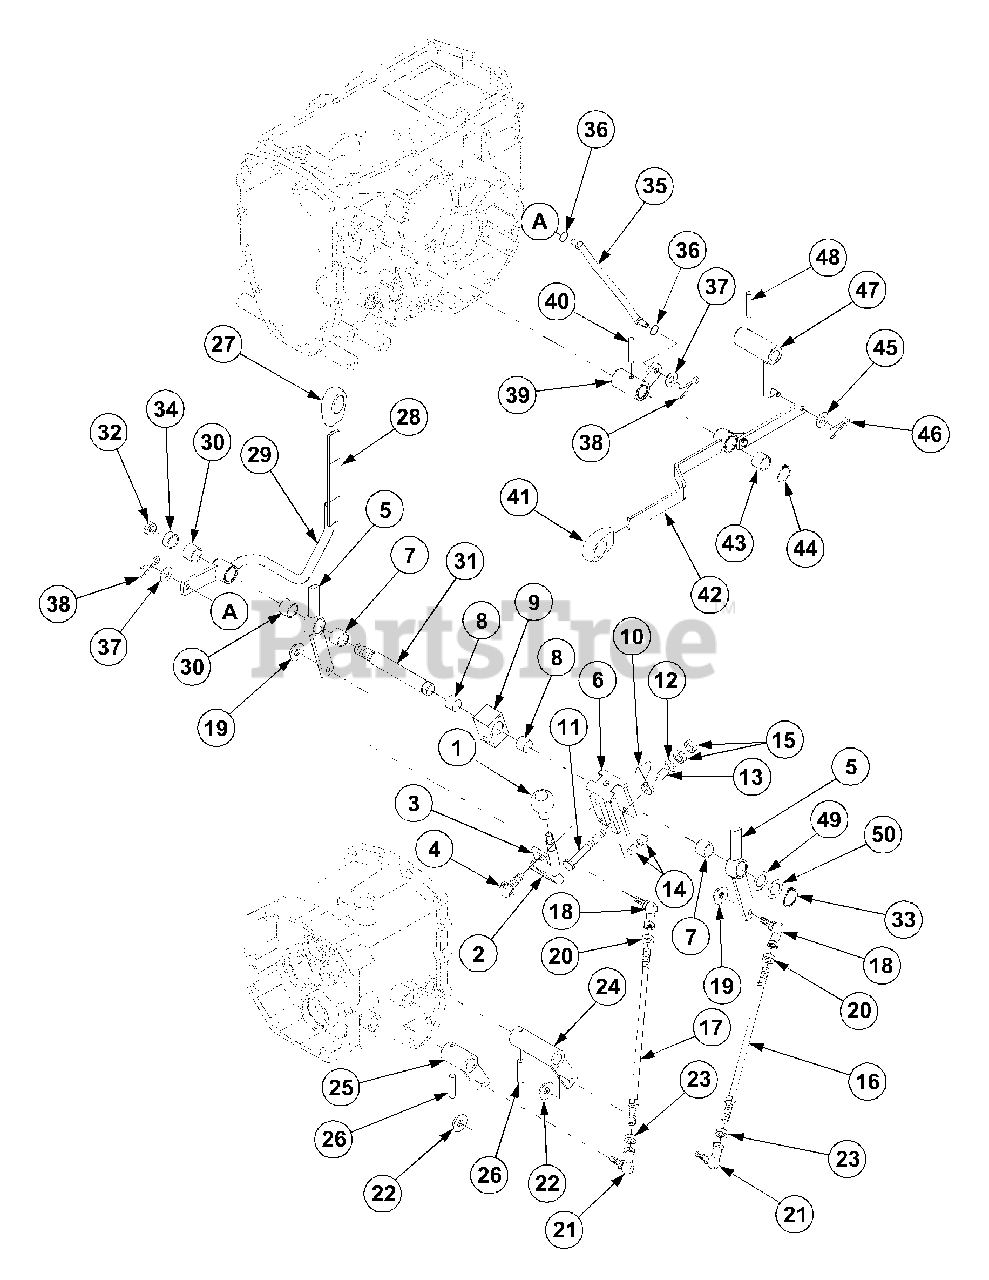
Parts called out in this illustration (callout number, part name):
4	Bolt,w/Washer
16	Rod,Main(1-2)
17	Rod,Main(3-4)
24	Link,Main(1-2)
25	Link,Main(3-4)
31	Shaft,Main.Sub
